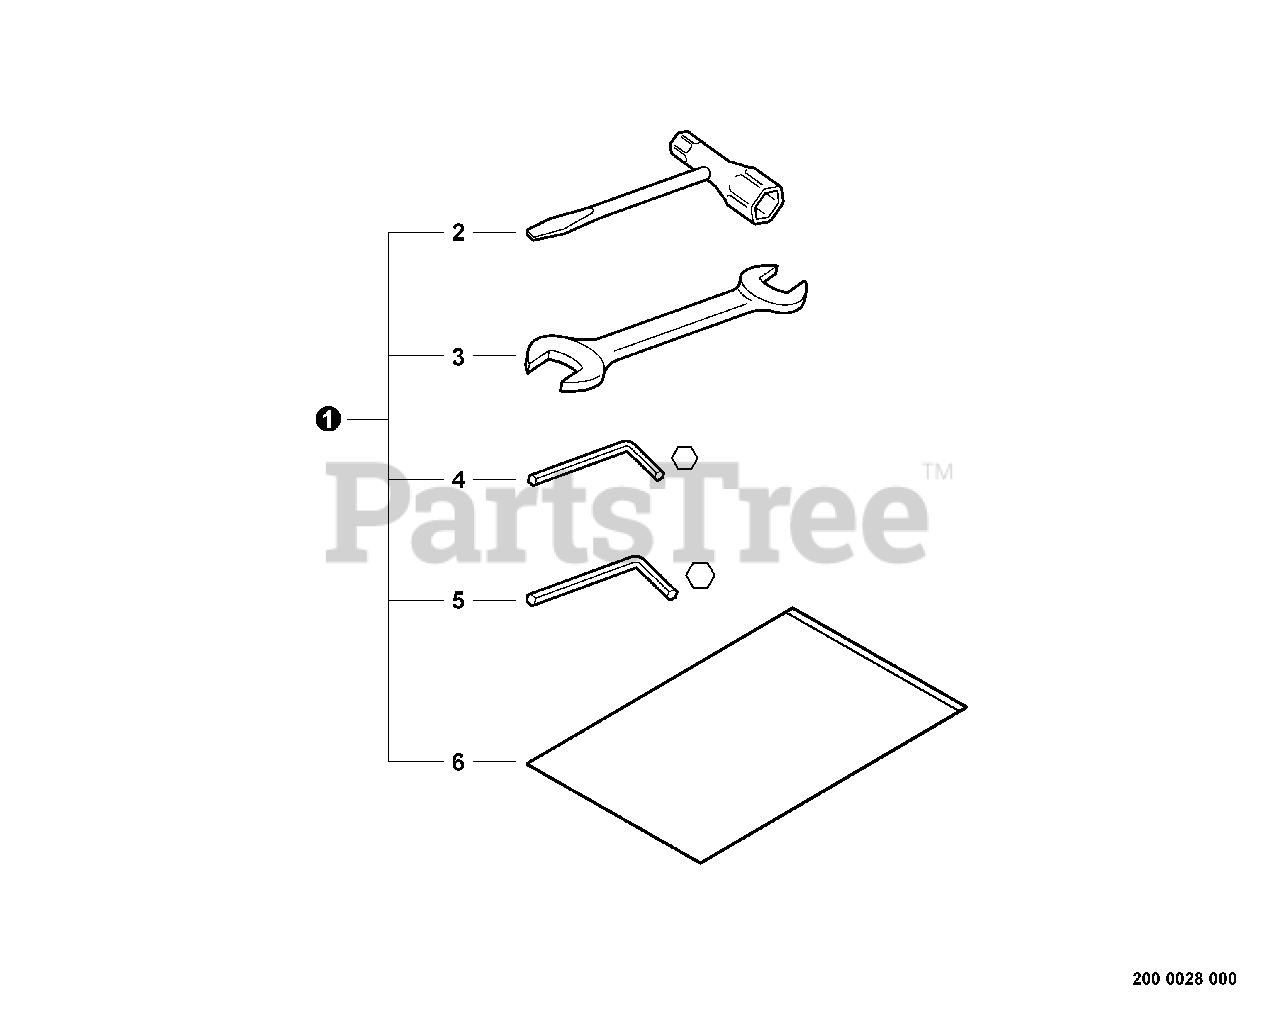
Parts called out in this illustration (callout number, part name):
1	TOOL KIT
2	T-WRENCH - 13X16mm
3	SPANNER - 8X10mm
4	HEX KEY - 3mm
5	HEX KEY - 4mm
6	BAG, TOOL
